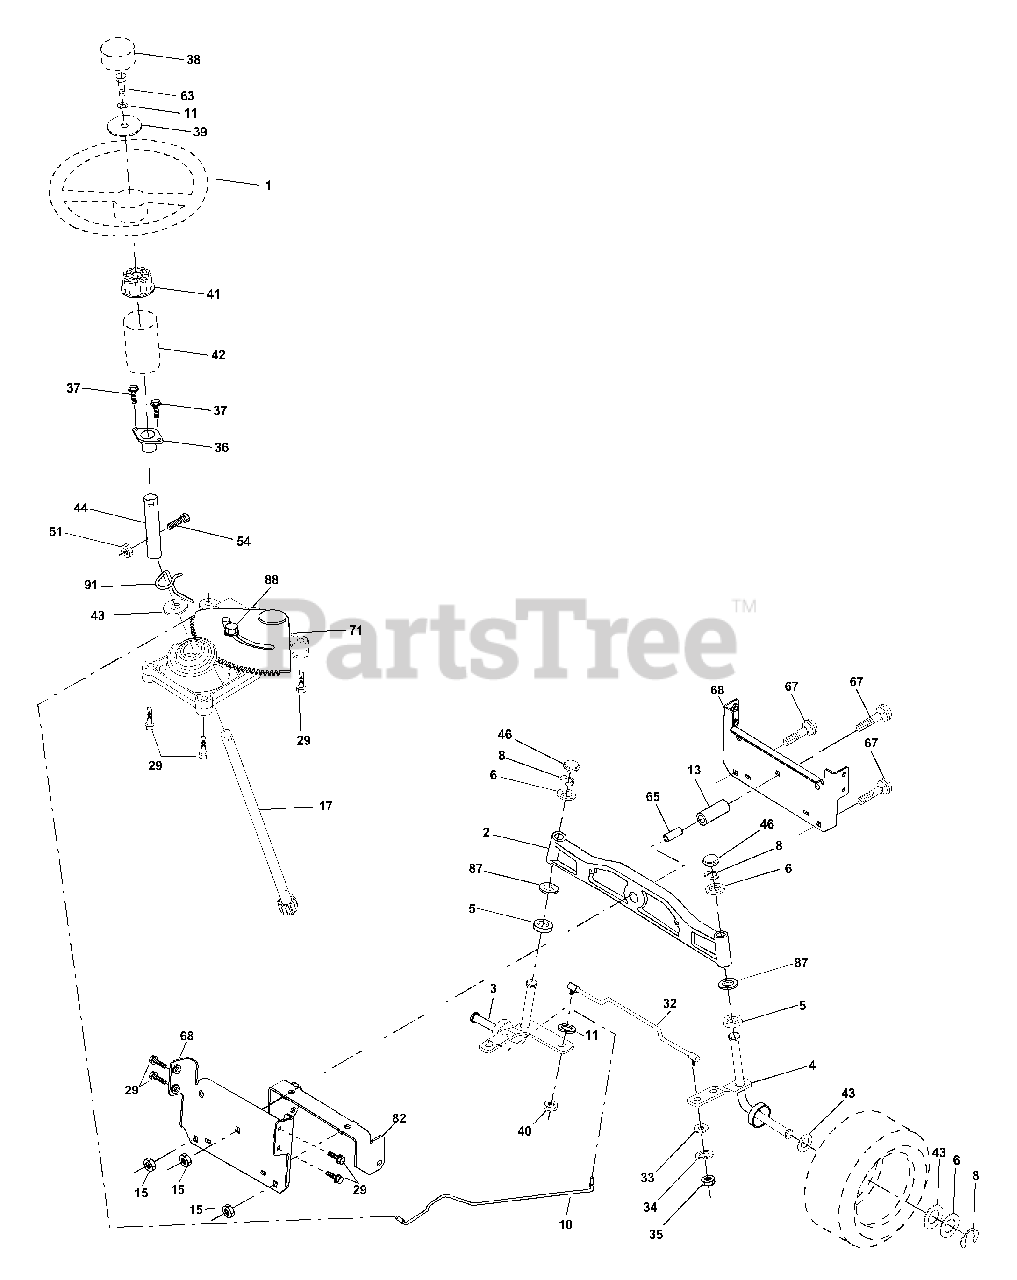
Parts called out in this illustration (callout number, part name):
1	Wheel Steering
2	Axle Asm Cast Iron LT
3	Spindle Asm LH
4	Spindle Asm RH
5	Bearing Race Thrust Harden
6	Washer 25/32 X 1-5/8 X 16 Ga
8	Ring Klip #t5304-75
10	Link Drag
11	Washer Lock Hvy Hlcl Spr 3/8
13	Spacer Brg Axle Front
15	Nut Hex Flange Lock
17	Shaft Asm Steering
29	Screw 3/8-16 x .75
32	Rod Tie
33	Washer 11/32 x 3/4 x 16 Ga
34	Washer Lock Hvy Hlcl Spr 5/16
35	Crownlock Nut 5/16-24 Unf
36	Bushing Strg
37	Screw
38	Insert Cap Strg Wh
39	Washer 13/32 X 1-1/20 X 11 Ga
40	Lock nut
41	Adaptor Wheel Strg
42	Boot Steering Dash
43	Washer 25/32 X 1 1/4 X 16 Ga
44	Extension Steering Shaft LR/LT
46	Cap Spindle Fr Top Blk
51	Nut Lock Hex w/Ins 5/16-18
54	Bolt Fin Hex 5/16-18 Unc x 1-1/4
63	Bolt Fin Hex 3/8-16unc x 1 Gr. 5
65	Spacer Brace Axle
67	Bolt Rdhd Sq 3/8-16 Unc x 2-3/4
68	Axle, Brace
71	Steering Asm
82	Bracket Susp Chassis Front
87	Washer Flat .781 x 1-1/2 x .14
88	Bolt Shoulder 7/16-20 Unc
91	Clip Steering
